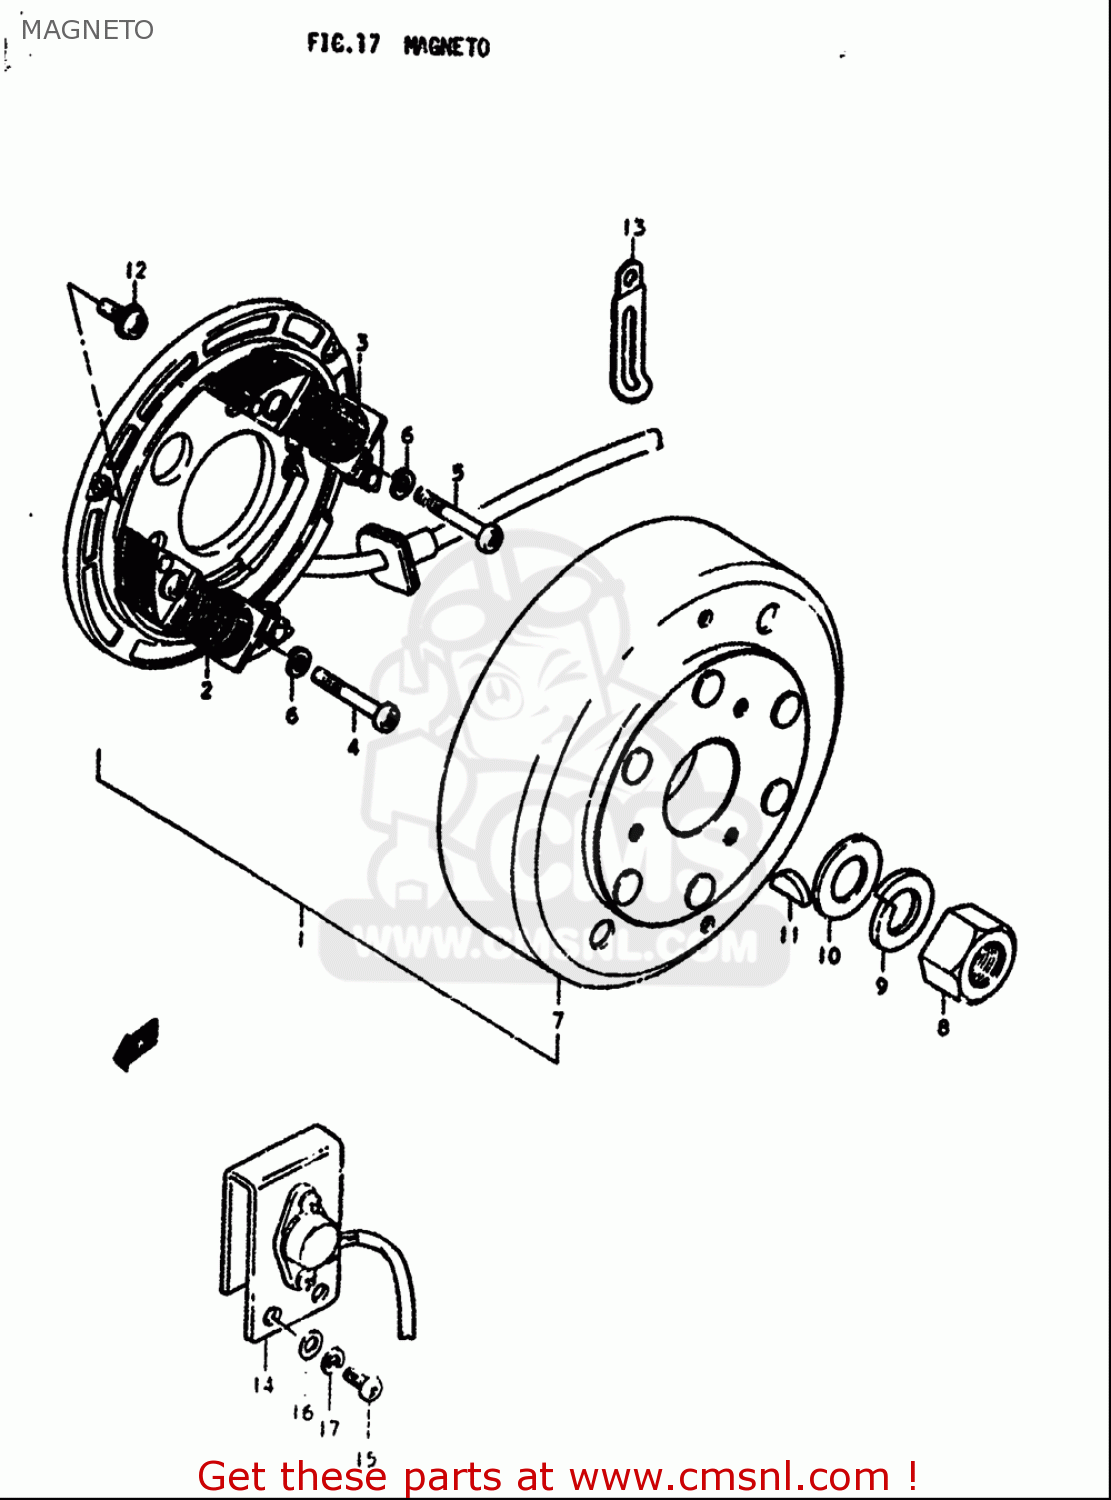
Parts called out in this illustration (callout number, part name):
2	STARTER ASSY
4	SCREW
5	SCREW
6	LOCK,WASHER
8	NUT
9	WASHER,LOCK
10	WASHER(14X27X3)
11	KEY
12	SCREW(5X14)
13	CLAMP(L:65)
14	REGULATOR ASSEMBLY
15	SCREW
16	WASHER
17	WASHER,LOCK
